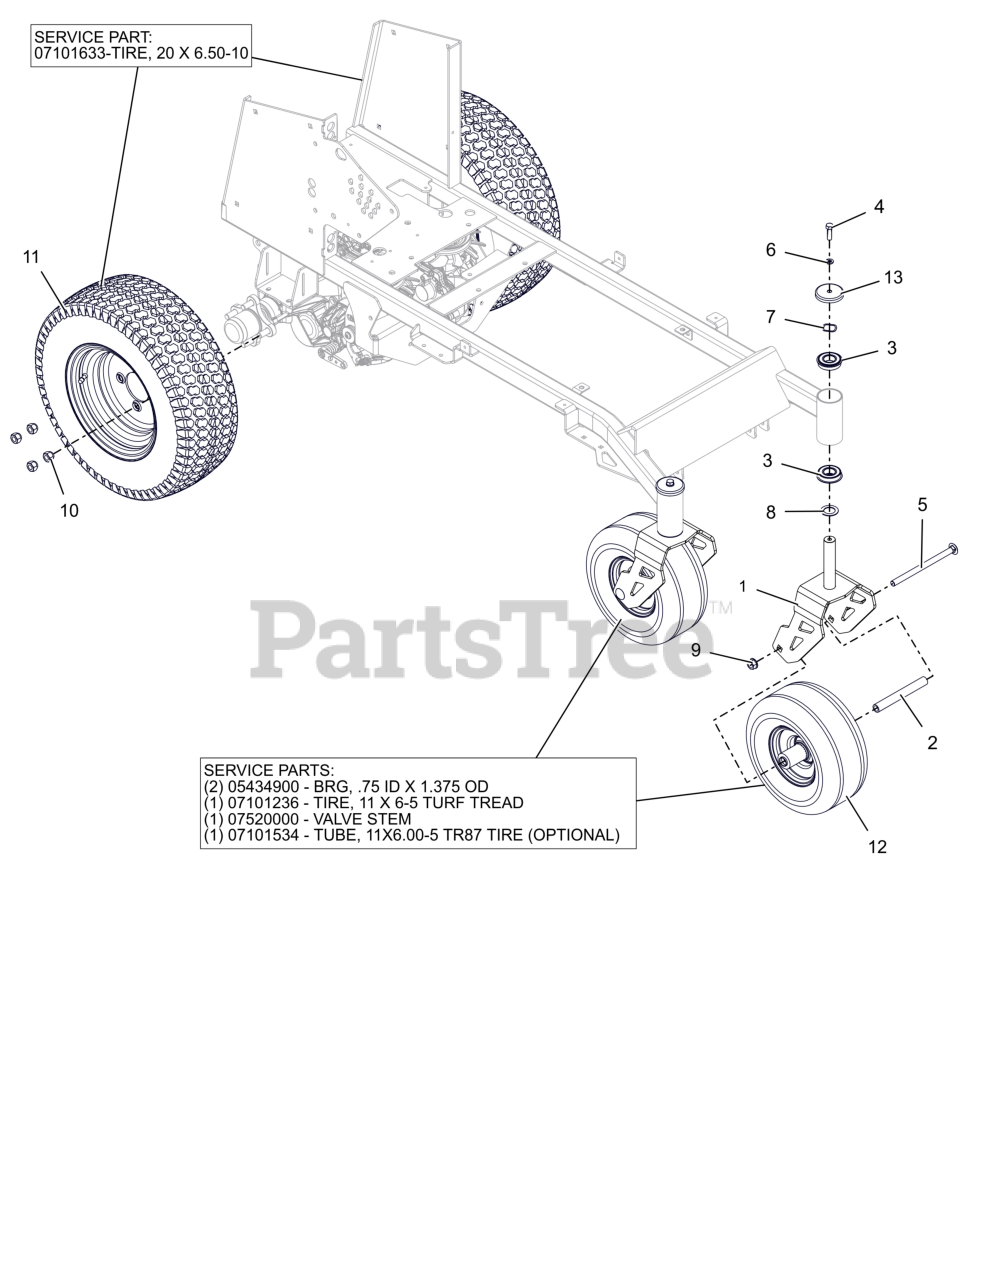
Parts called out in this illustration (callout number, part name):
1	WLDMT- CASTOR FORK
2	SPACER, FRONT WHEEL (WIDE 6.0)
3	BEARING, BALL -2.000 OD X 1.000 ID X .5625 W/RING
4	BLT- HEX .38-16X1.25 G5 ZB500
5	BLT-RHSN .50-13X7.50 G5 ZCC NS
6	WSHR-LK-REG .375X.094 ZB500
7	WSHR-WAVE 1.0X1.25X.028 .145FH
8	WSHR-HRD-THRS 1.007X1.542X.062
9	NUT-LK-CTR-FLG .500-13 GG ZCC
10	NUT, WHEEL .50-20 ZCC
11	ASSM TIRE\WHEEL, ASM 20 X 6.50 - 10
11	TIRE, 20 X 6.50-10
11	VALVE STEM ASS'Y
12	ASM- WHL/TIRE 11 X 6.00-5 BLACK
12	BRG-BALL .752X1.380X.500
12	LAWN TIRE FRONT, 11/6.00-5 SMOOTH
12	VALVE STEM ASS'Y
12	TUBE- 11X6.00-5 TR87 TIRE
13	SHIELD, AXLE BEARING
